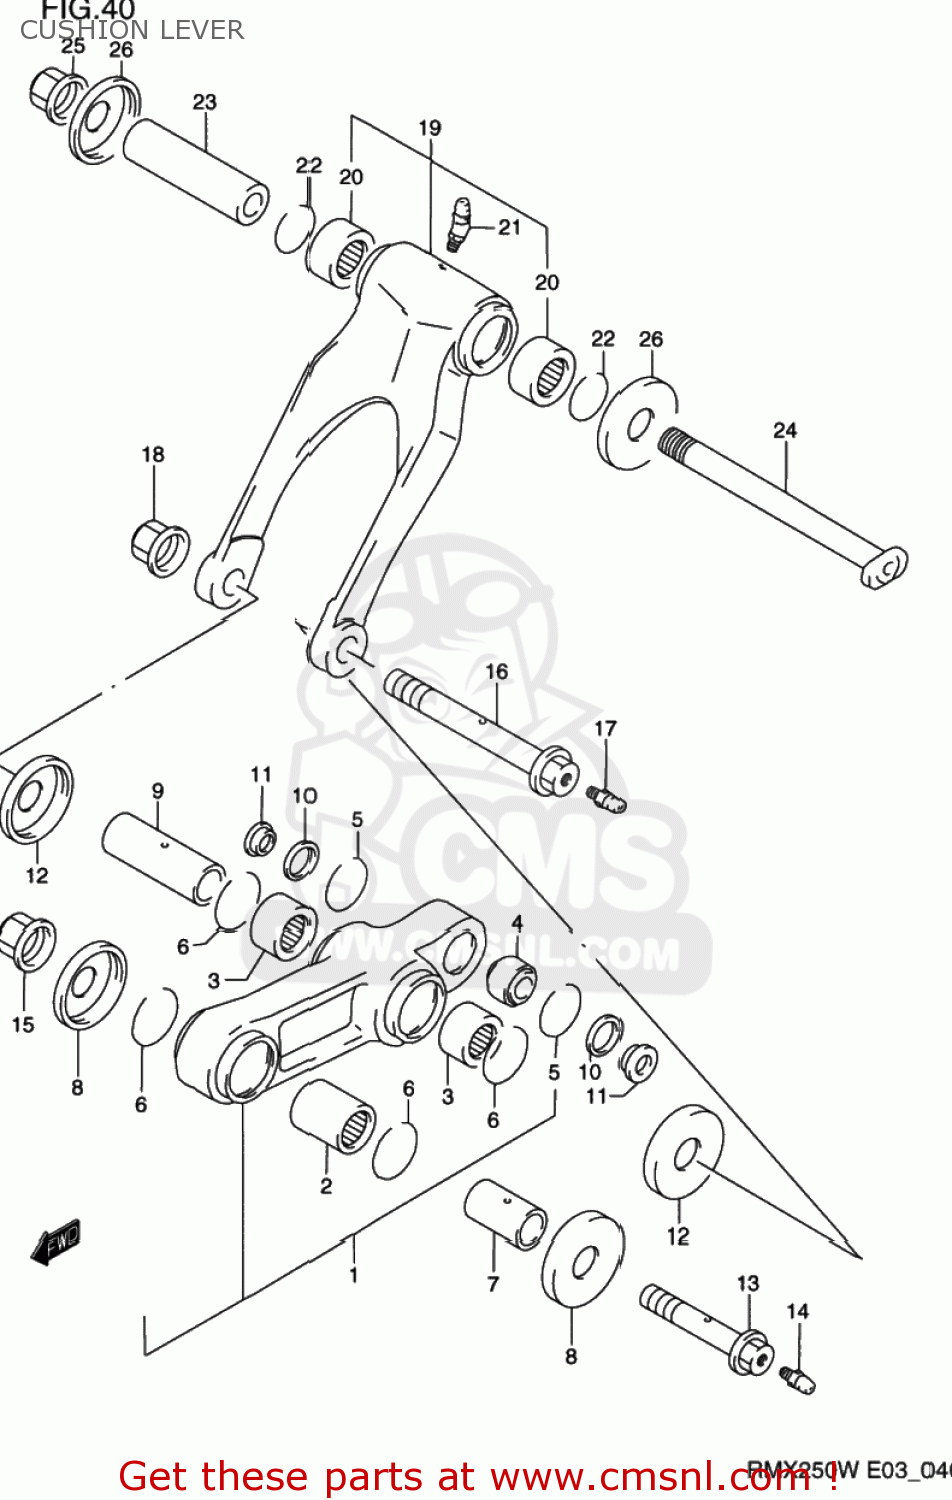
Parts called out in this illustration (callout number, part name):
1	LEVER SET,RR CUSHION
2	BEARING(20X27X25)
3	BEARING(21X27X20)
4	BEARING,RR CUSHION LEVER RR
5	RING,BEARING STOPPER
6	CIRCLIP
7	SPACER,RR CUSHION LEVER FR
8	SEAL,RR CUSHION LEVER FR DUST
9	SPACER,RR CUSHION LEVER CTR
10	SEAL,RR CUSHION LEVER RR DUST
11	SPACER,RR CUSHION LEVER RR
12	SEAL,REAR CUSHION LEVER
13	BOLT SET,RR CUSHION LEVER FR
14	GREASE NIPPLE
15	NUT 12MM
16	BOLT,RR CUSHION LEVER CTR
17	GREASE NIPPLE
18	NUT
19	ROD SET,RR CUSHION LEVER
20	BEARING(21X27X20)
21	NIPPLE,GREASE
22	CIRCLIP
23	SPACER,RR CUSHION ROD
24	BOLT,RR CUSHION ROD
25	NUT
26	SEAL,REAR CUSHION LEVER
